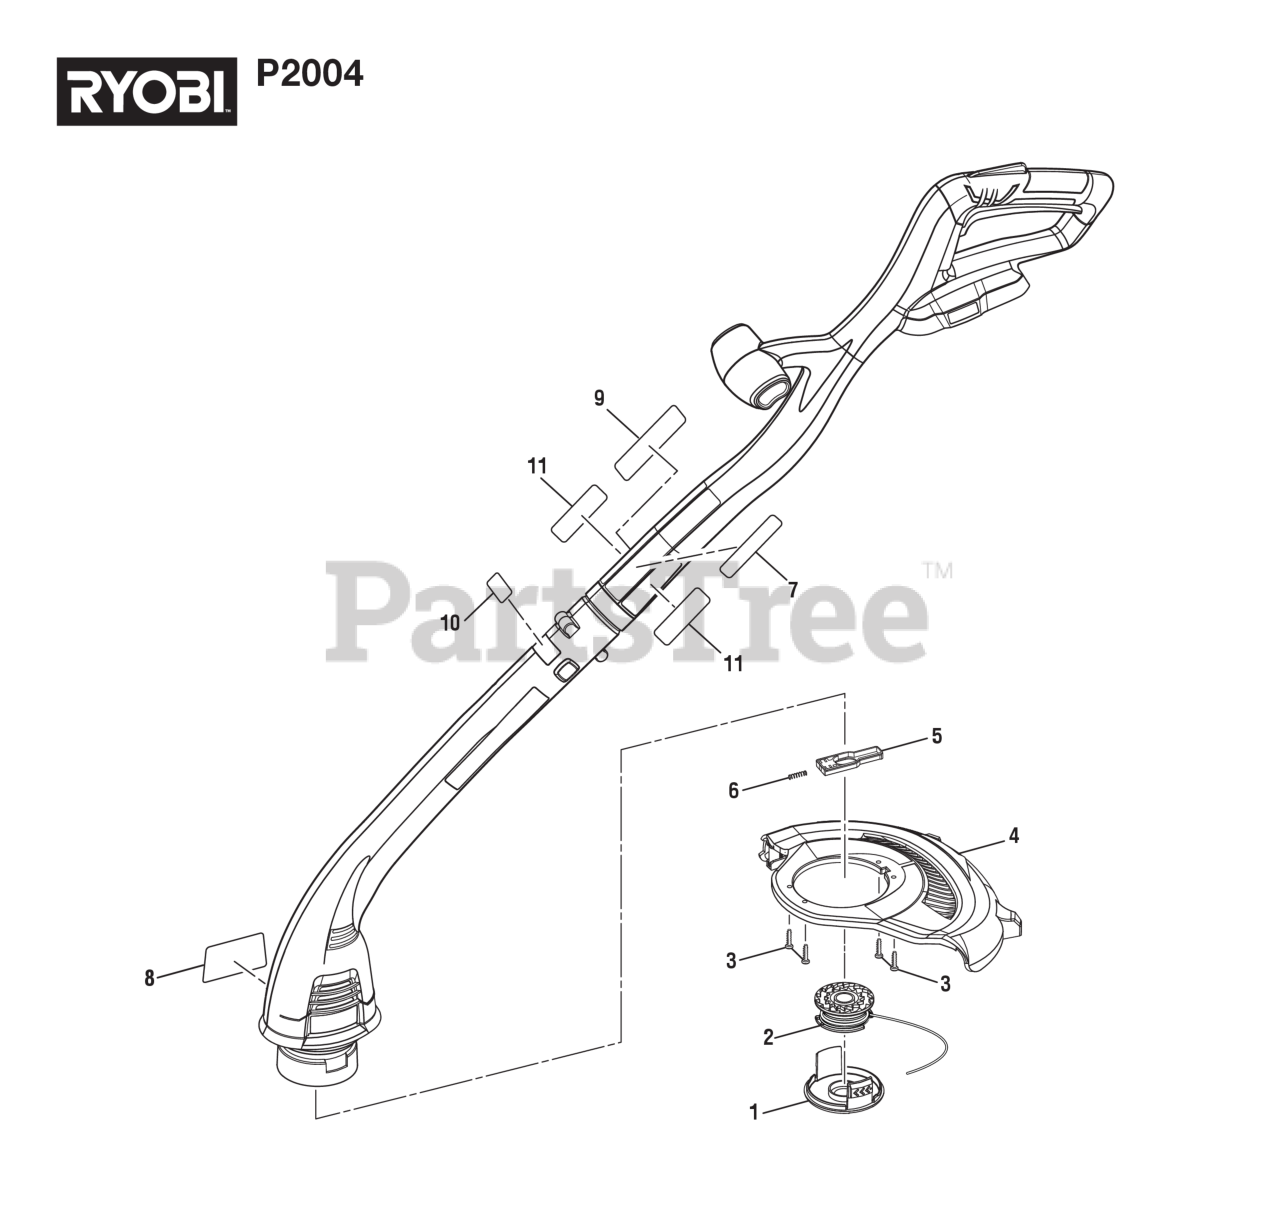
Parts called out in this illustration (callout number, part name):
1	Spool Cap (AC14HC)
2	Spool Assembly (.065 round-RY40021)
3	Screw (M4 x 12 mm, Pan Hd.)
4	Guard with Blade Assembly
5	Plastic Slider with Metal Inset Assembly
6	Compression Spring (Internal Tooth)
7	Label, Warning Icon
8	Label, Data
9	Label, Warning, Translation
10	Pivoting Arrow Label
11	Label, Ryobi Logo, Handle
